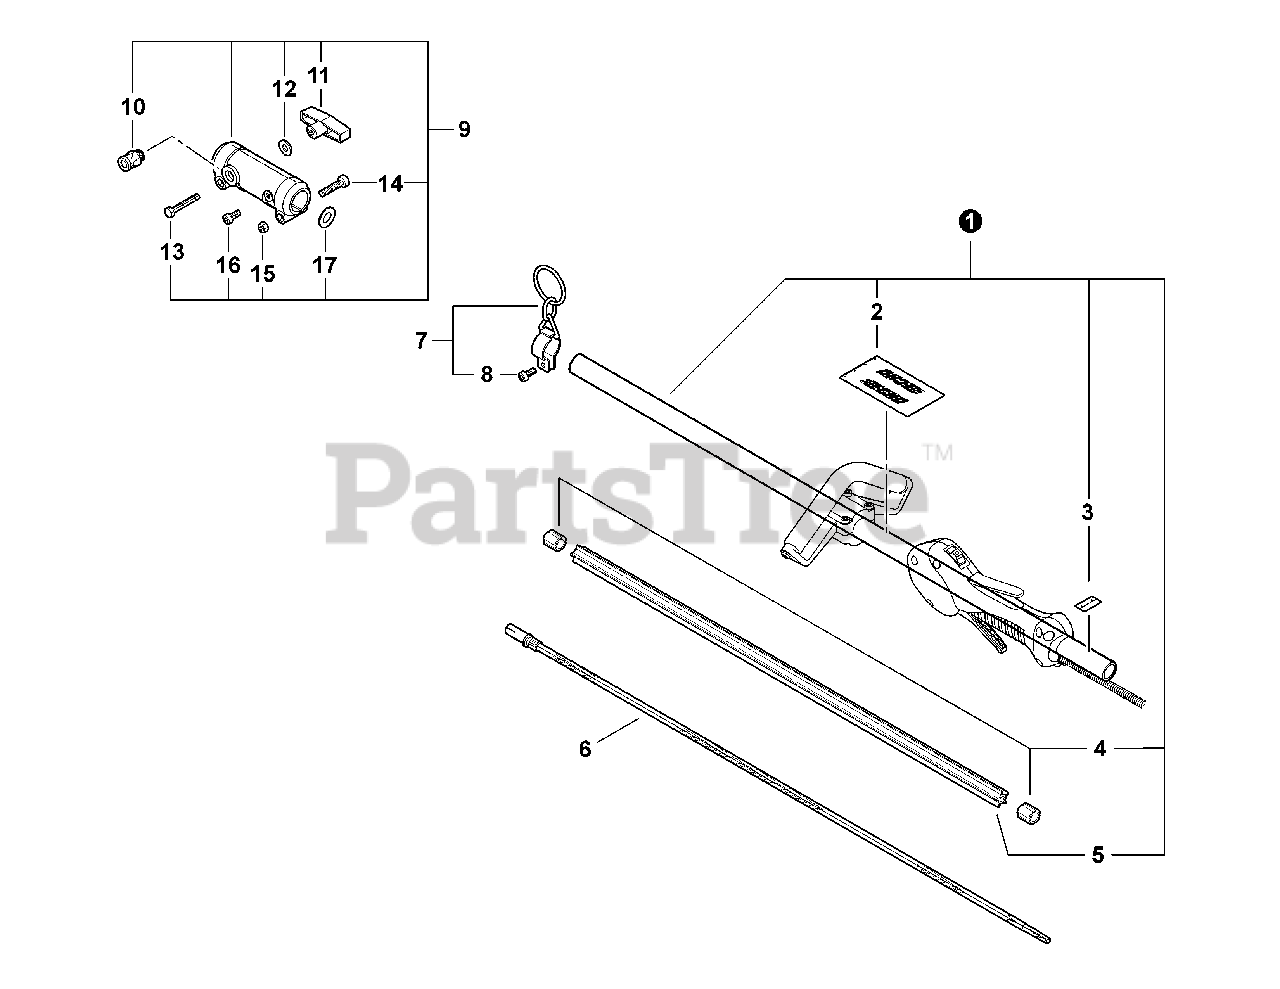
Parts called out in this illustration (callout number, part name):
1	MAIN PIPE ASSY
2	LABEL - HANDLE LOCATION
3	LABEL - ALIGNMENT
5	LINER - FLEXIBLE
6	DRIVESHAFT - FLEXIBLE
7	HARNESS HANGER KIT
8	SCREW - 5X12
9	COUPLER ASSY
10	LATCH ASSY
11	WINGNUT
12	WASHER - 6
13	BOLT - 6X40
14	SCREW - 6X25
16	SCREW - 5X10
17	WASHER - 18
